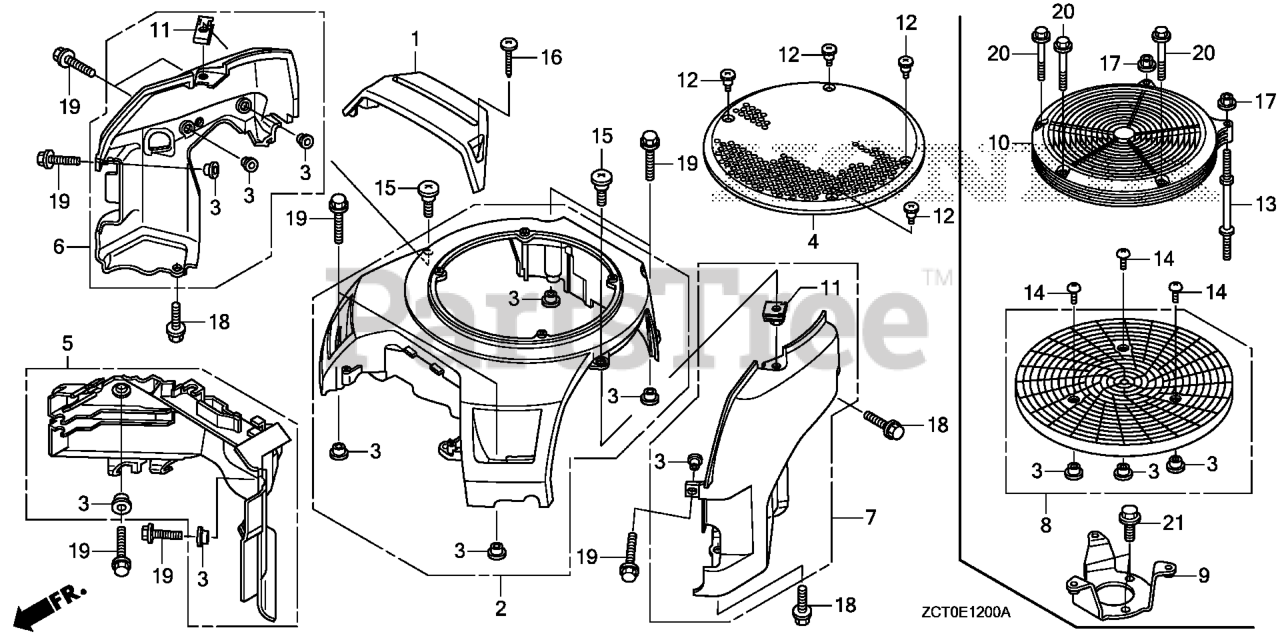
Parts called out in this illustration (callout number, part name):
1	COVER, FUEL PUMP
2	COVER, FAN *R280* (POWER RED)
2	COVER, FAN *NH1* (BLACK)
3	COLLAR, FAN COVER
5	SHROUD (UPPER)
6	SHROUD, R. (LOWER)
7	SHROUD, L. (LOWER)
8	GRID, SCREEN
9	HOLDER, SCREEN GRID
10	COVER, SCREEN GRID
11	NUT, FENDER SETTING
13	BOLT, STUD
14	SCREW, TRUSS (6X16)
15	SCREW, SPECIAL (6X15)
16	SCREW, TAPPING (5X20)
17	NUT, FLANGE (6MM)
18	BOLT, FLANGE (6X16) Use from Engine SN 2056820.
19	BOLT, FLANGE (6X20)
20	BOLT, FLANGE (6X40)
21	BOLT, FLANGE (8X18) Use from Frame SN 1256673.
